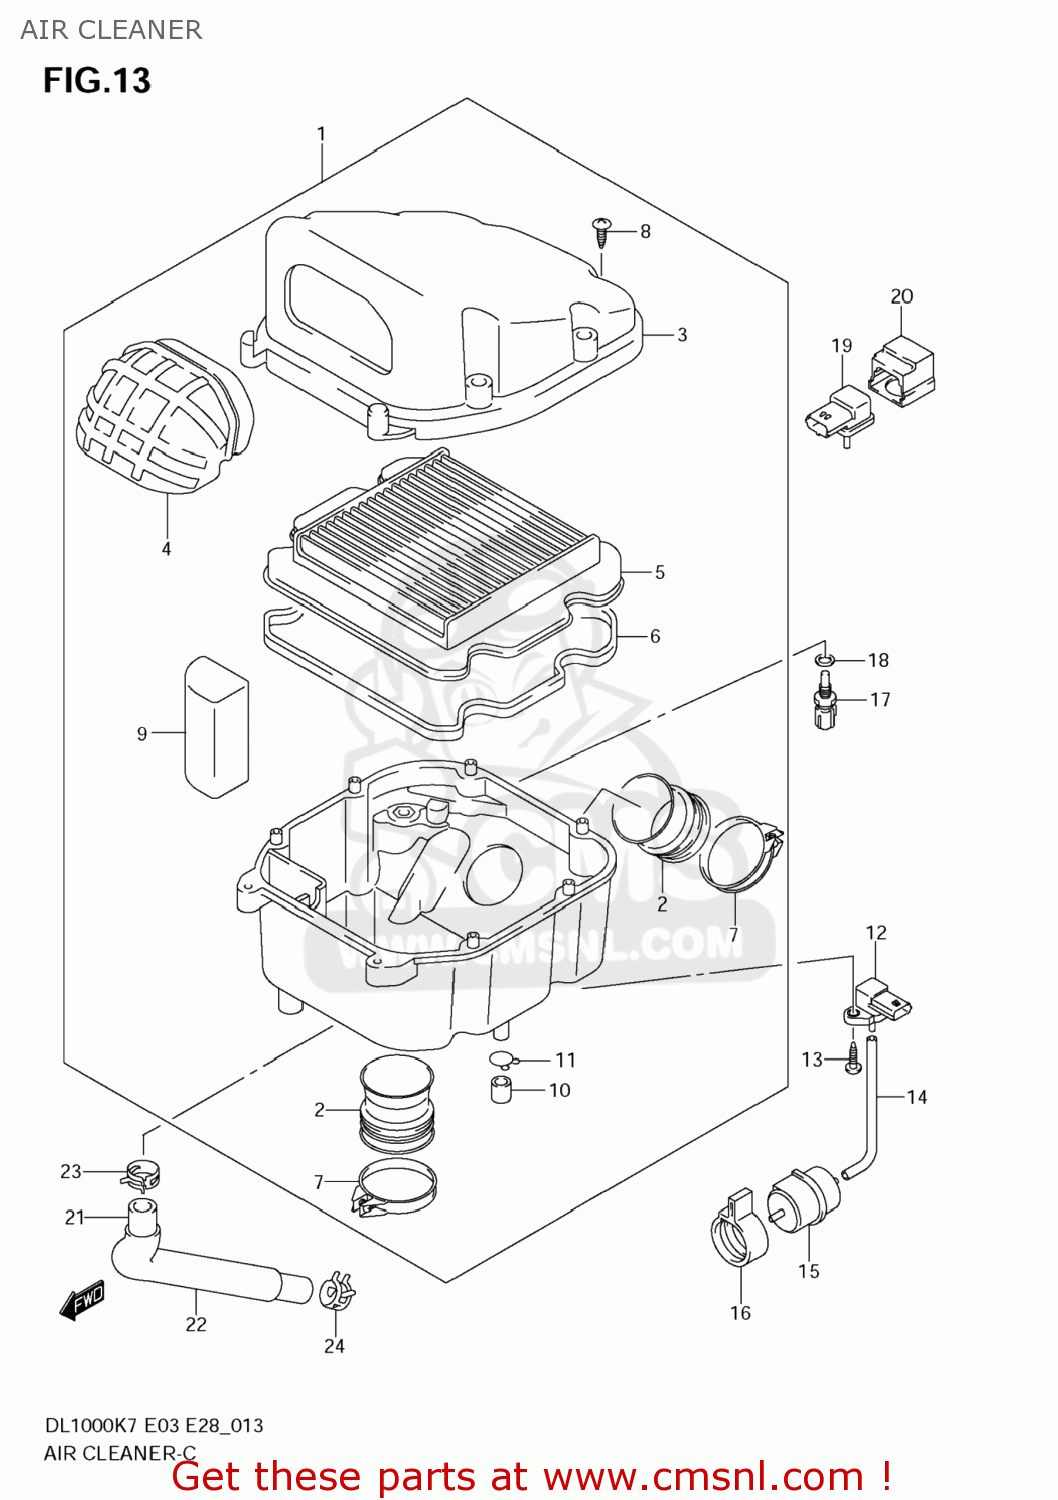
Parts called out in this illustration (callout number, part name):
1	CLEANER ASSY,AIR
2	TUBE,OUTLET
3	CAP,AIR CLEANER
4	TUBE,INLET
5	FILTER,AIR CLEANER
6	GASKET,AIR CLEANER (NAS)
7	CLAMP,OUTLET TUBE FR
8	SCREW
9	FILTER, BREATHER
10	PLUG
11	CLIP
12	SENSOR,PRESSURE
13	SCREW
14	HOSE,AIR VALVE
15	CHAMBER,VACUUM
16	BAND,VACUUM CHAMBER
17	SENSOR,WATER TEMP
18	GASKET(12X17X1) (NAS)
19	SENSOR,PRESSURE
20	HOLDER,SENSOR
21	TUBE,BREATHER
22	PROTECTOR,BREATHER TUBE
23	CLIP
24	CLAMP
